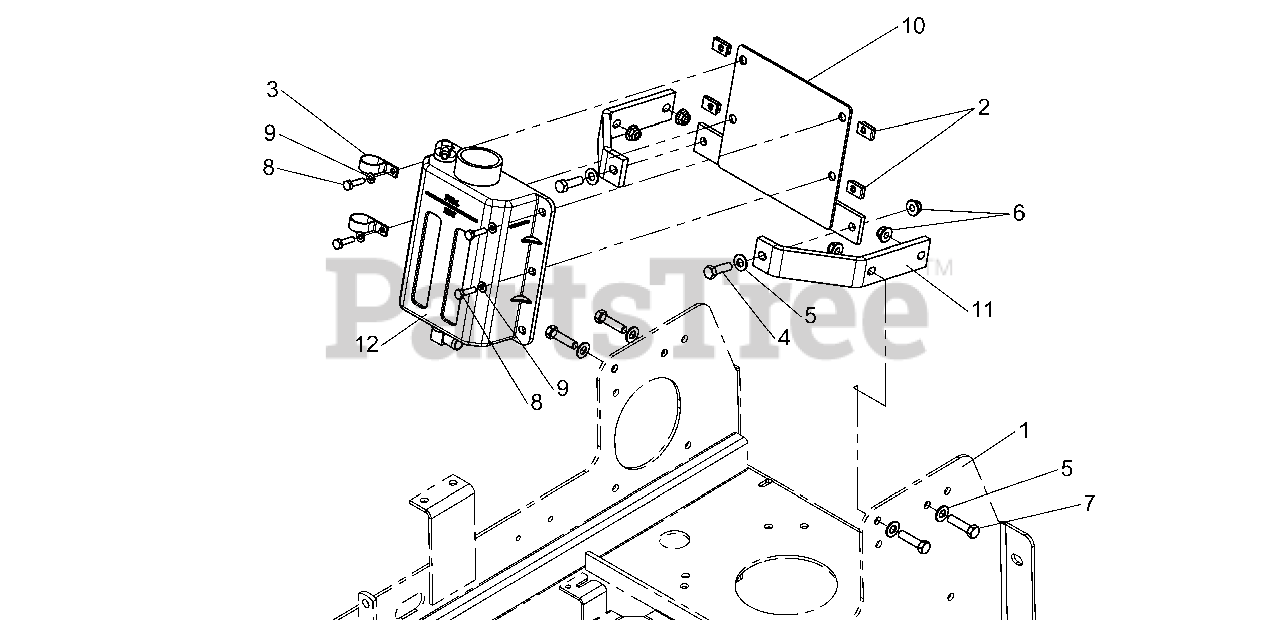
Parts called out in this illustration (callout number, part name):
1	MAIN FRAME (See Main Frame Group)
2	BODY CLIP, 1/4-20
3	CLAMP, Vinyl Insulated
4	BOLT, 3/8-16 X 1-1/4"
5	WASHER, 3/8" SAE
6	NUT, 3/8-16 Hex Nylock Flange
7	BOLT, 3/8-16 X 1-1/2"
8	BOLT, 1/4-20 X 1", GD
9	WASHER, 1/4 SAE (5025154)
10	HYDRAULIC TANK MOUNT
11	MOUNT BRACKET
12	HYDRAULIC TANK (See Hydraulic Group)
